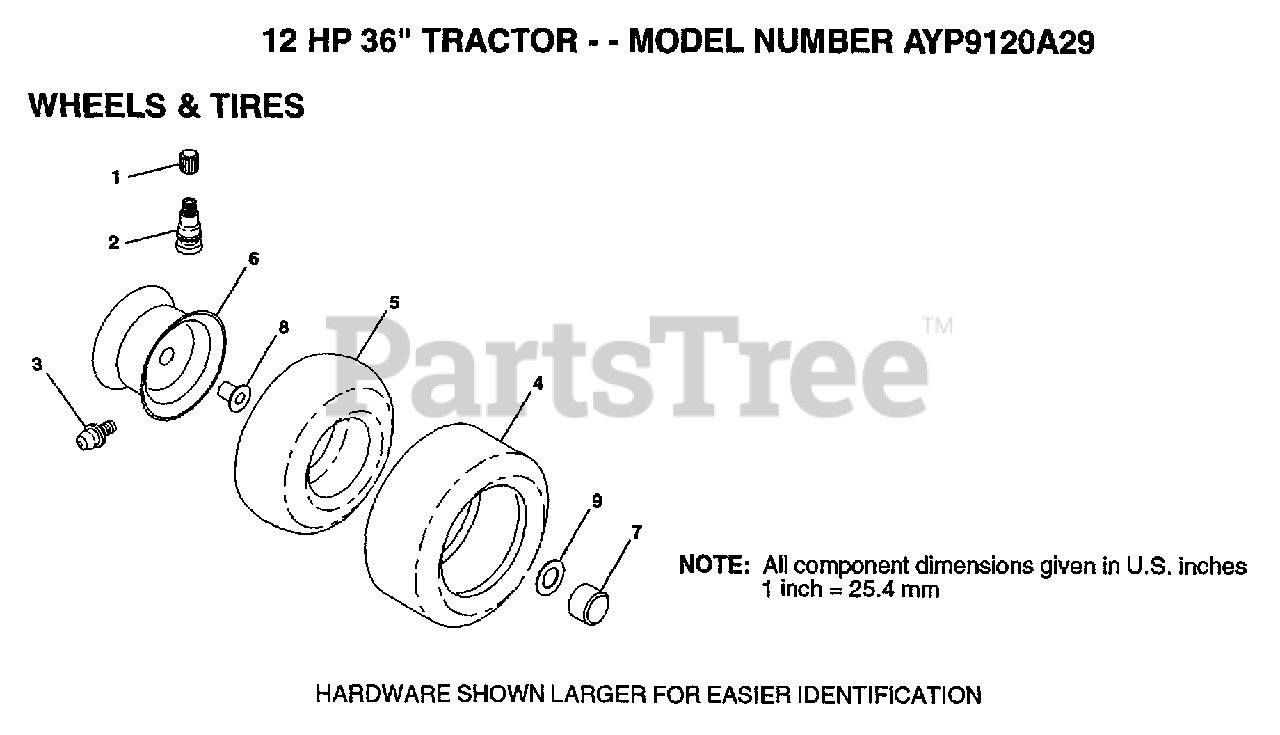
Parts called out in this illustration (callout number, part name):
1	VALVE CAP
2	VALVE STEM LT
3	FITTING LT
5	TUBE.5.3/4.5/6
7	HUB CAP
8	"FLANGE, BEARING"
9	WASHER
